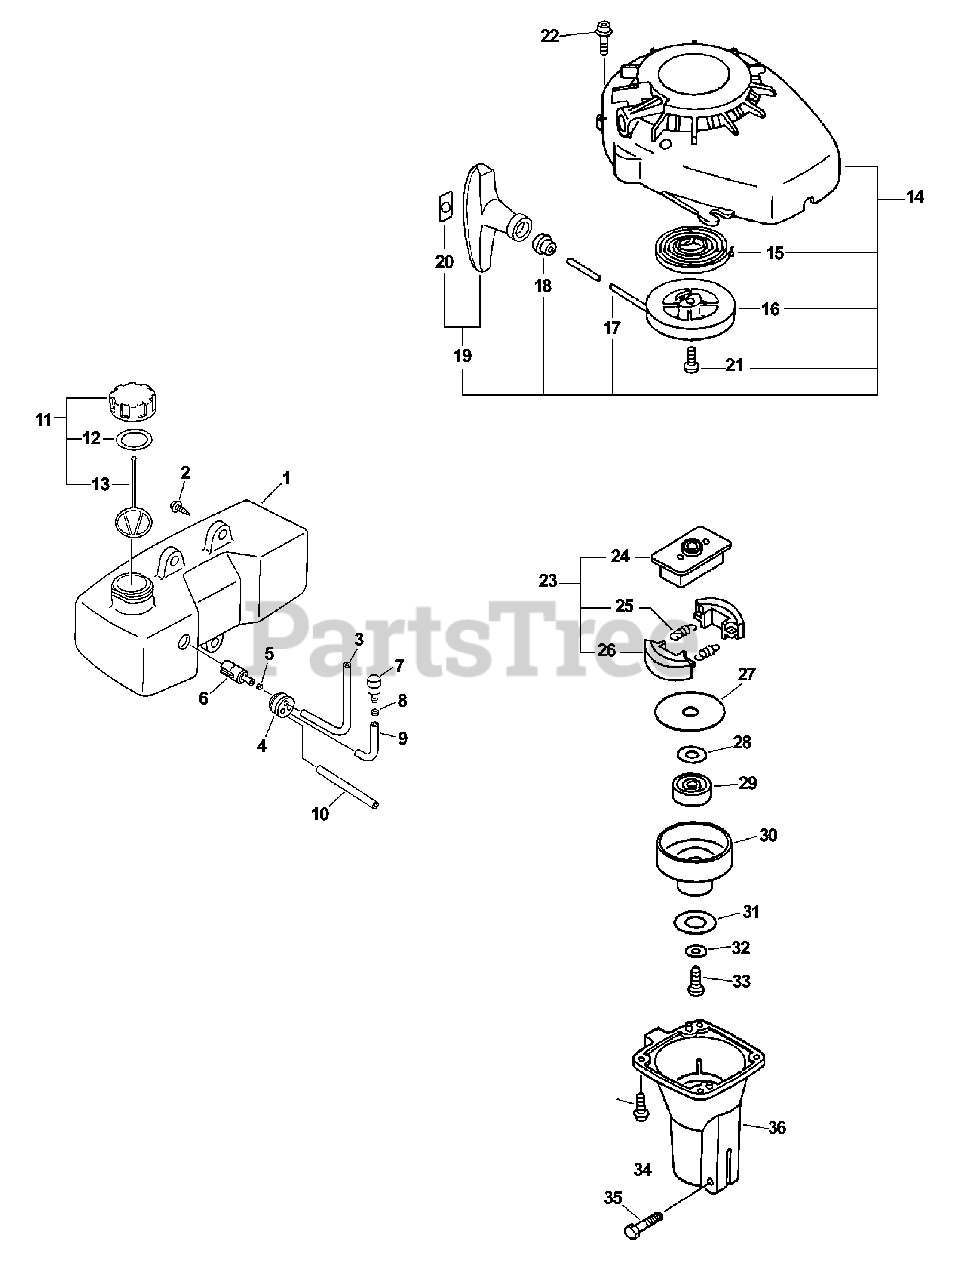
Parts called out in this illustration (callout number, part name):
1	TANK ASSY, FUEL
2	SCREW 5×15
3	PIPE, FUEL 3×5×210 BLACK
4	GROMMET, FUEL
5	CLIP 6 MM
6	FILTER, FUEL
7	VENT ASSY
9	PIPE, FUEL 3x-5x-70 BLACK
10	PIPE, FUEL 3×6×50
11	CAP ASSY
12	GASKET, FUEL CAP
13	CONNECTOR, CAP L= 100 MM
14	STARTER ASSY
15	SPRING, RECOIL
16	REEL, ROPE
17	ROPE, STARTER
18	GUIDE, ROPE
19	GRIP, STARTER
20	RETAINER, ROPE
21	SCREW
22	SCREW 4×16
23	CLUTCH ASSY
24	HUB, CLUTCH
25	SPRING, CLUTCH
26	SHOE, CLUTCH
27	PLATE, CLUTCH
28	WASHER 10.5×18×1.6
29	BEARING, BALL 6000-2RLB
30	DRUM, CLUTCH
32	WASHER, CLUTCH
33	SCREW 6×12
34	SCREW 4×14
35	BOLT 5
36	CASE, CLUTCH
